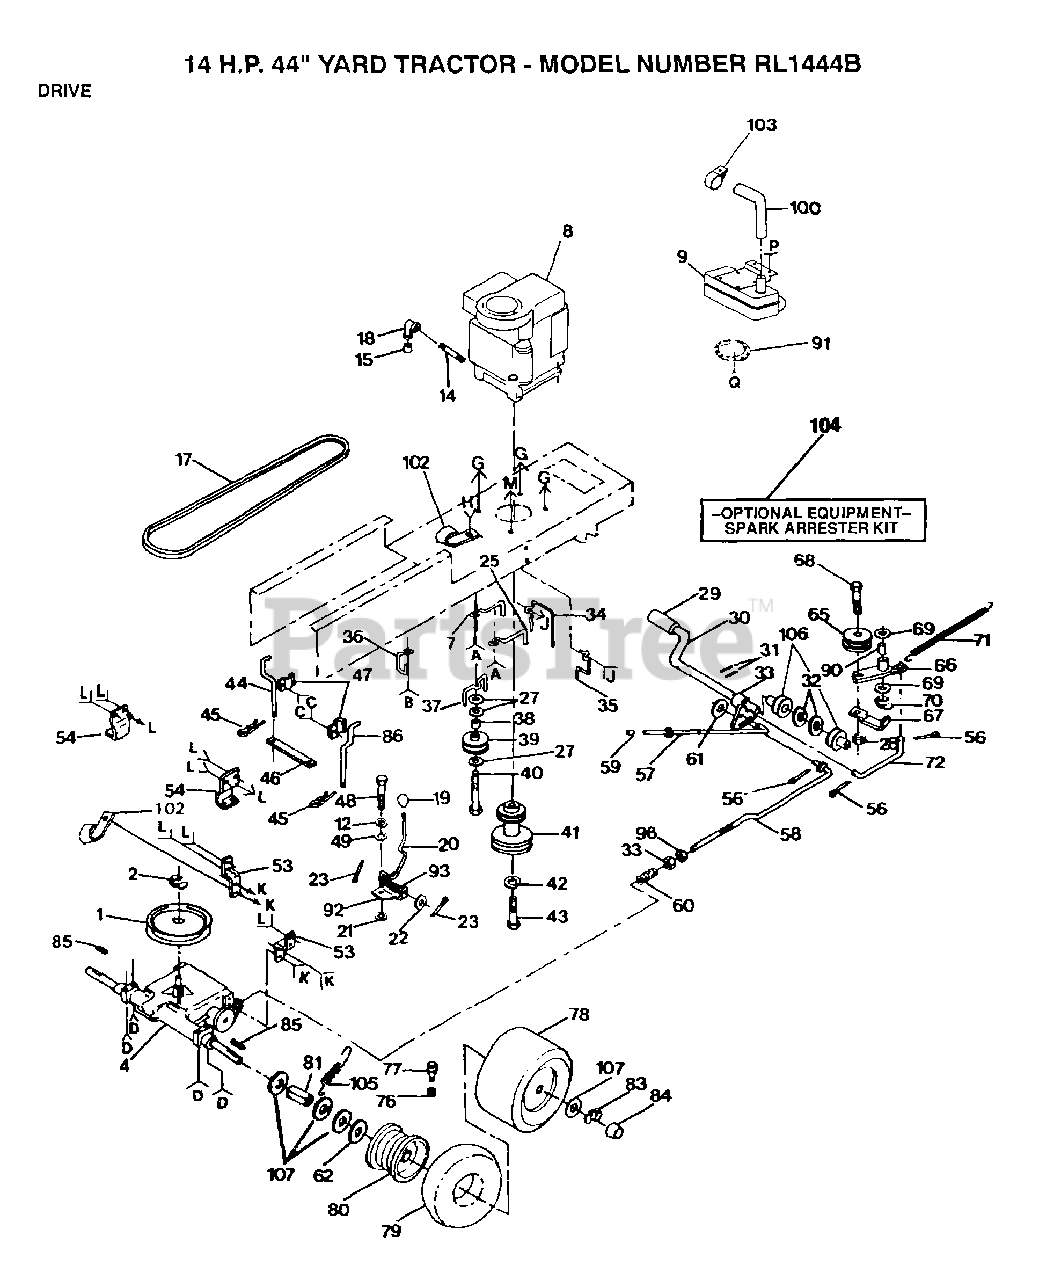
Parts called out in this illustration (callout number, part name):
1	PULLEY TRANS
7	KEEPER BELT ENGLH
12	LOCKWASHER
14	PIPE NIPPLE
17	BELT-V.90.0.GD.DR
19	CONTROL KNOB LT
21	WASH-SHFT PLT LT
22	WASHER
23	PIN COTTER 1/8
25	"KEEPER,BLT ENG LT"
27	WASHER
29	PEDAL COVER T
32	WASHER LT
33	NUT
34	BELT GUIDE
35	BELT GUIDE
37	BELT KEEPER LT
38	SPACER T
39	PULLEY.IDLER.FLAT
40	BOLT
42	LOCKWASHER
43	BOLT
44	KEEPER BELT LH
45	SPRING.RETAINER
46	STRAP LOCATOR
47	CLAMP LT
49	WASHER LT
53	STRAP TORQUE
54	BRACKET LT
56	COTTER PIN
58	BRAKE ROD LT
60	SPRING ROD LT
61	WASHER
62	WASHER
66	ARM IDLER
67	RETAIN BELT
69	WASHER LT
70	KLIP RING
71	"SPRING, RETURN LT"
72	"LINK, CLUTCH T"
76	VALVE CAP
77	VALVE STEM LT
79	TUBE.18X9.5-8
81	SPACER LT
83	E-RING LT
84	HUB CAP
85	SQUARE KEY
86	KEEPER BELTRH
90	"LY, BEARING"
91	DEFLECTOR.222573
92	PLATE SHIFT LT
93	SPRING LT
98	WASHER
100	"TUBE,EXHAUST"
102	CLIP T
103	"CLAMP,MUFFLER"
104	SPARK ARREST KIT
106	NYLON BEARING
107	WASHER
